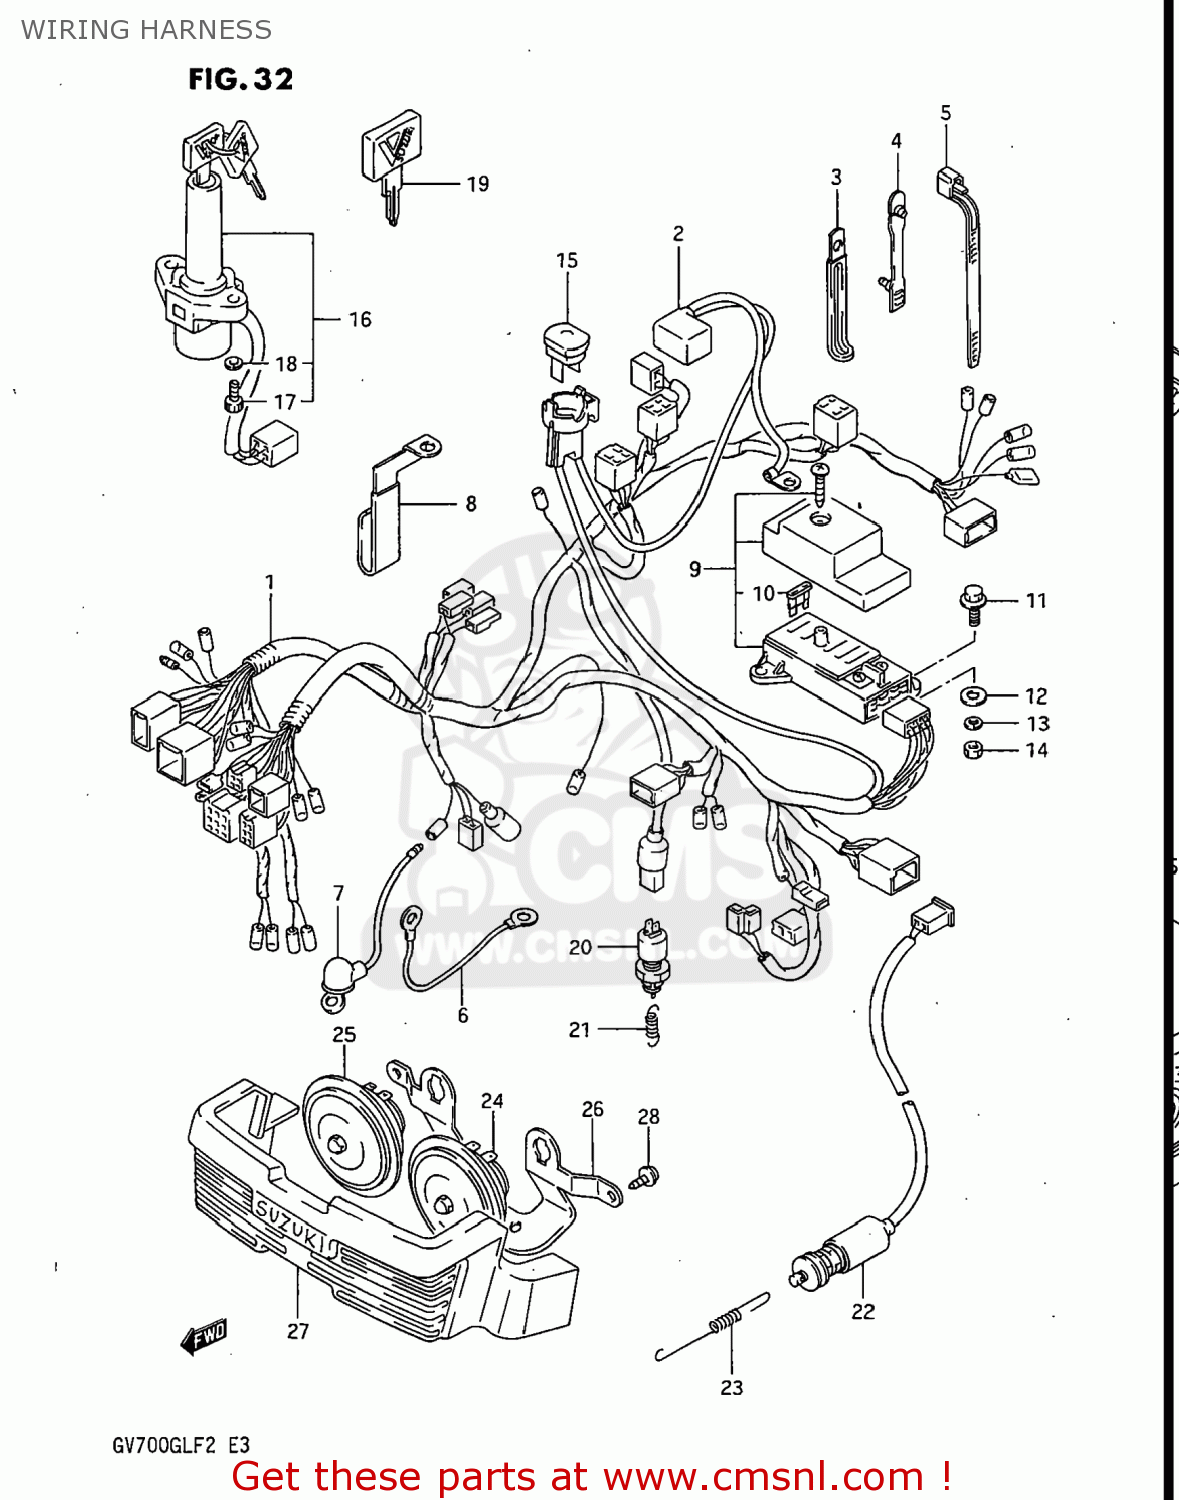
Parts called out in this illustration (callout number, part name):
1	HARNESS,WIRING
2	CAP,BATTERY PLUS TERMINAL
3	CLAMP
4	CLAMP,L:88
5	CLAMP(L:95)
6	WIRE
7	WIRE
8	CLAMP,WIRING HARNESS
9	BOX ASSEMBLY,FUSE
10	FUSE(10A)
11	BOLT
12	WASHER
13	WASHER,LOCK
14	NUT
15	BREAKER ASSY,CIRCUT
16	SWITCH ASSEMBLY,IGNITION
17	BOLT
18	WASHER,LOCK
19	KEY,BLANK
20	SWITCH ASSEMBLY,STOP LAMP
21	SPRING
22	SWITCH ASSEMBLY,SIDE STAND
23	SPRING
24	HORN ASSEMBLY,HIGH PITCH
25	HORN ASSEMBLY,LOW PITCH
26	BRACKET,HORN
27	COVER,HORN
28	SCREW
